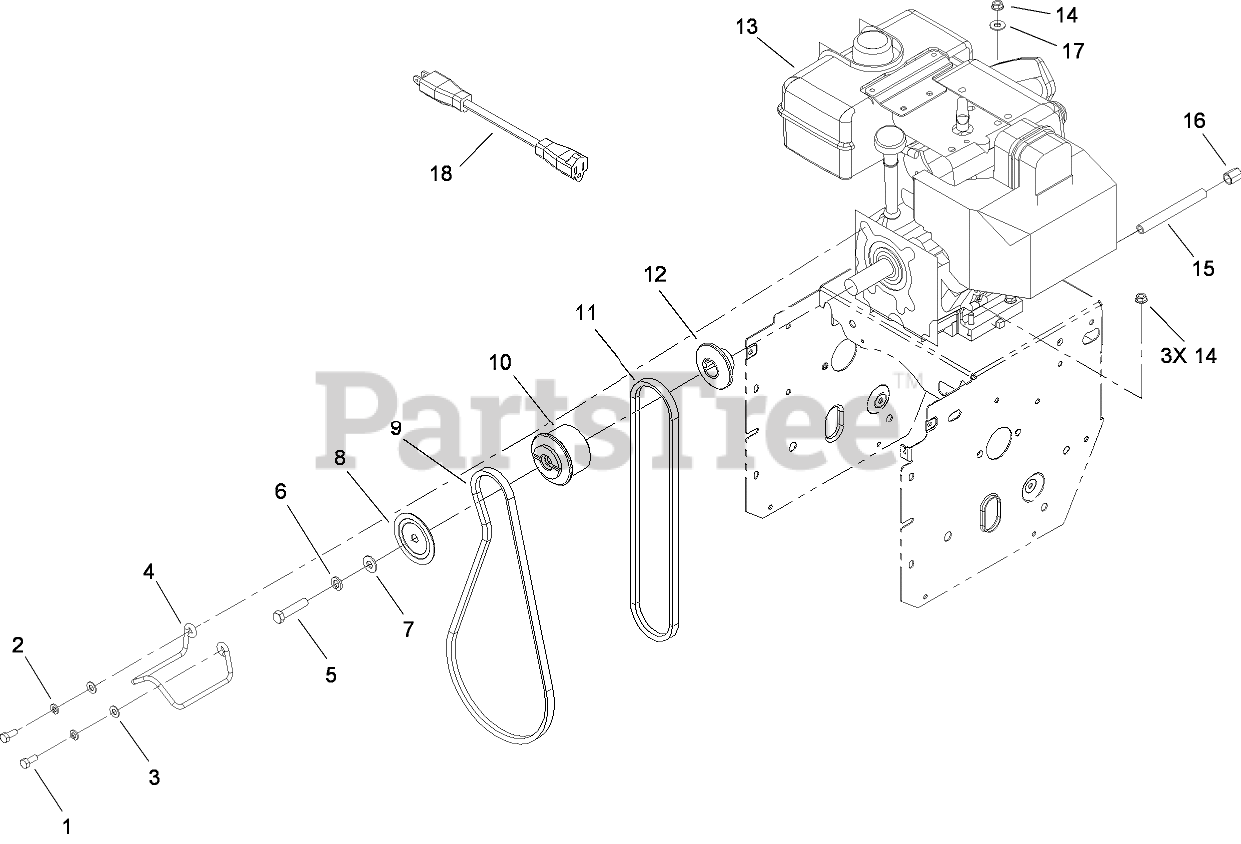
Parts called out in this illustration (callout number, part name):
1	SCREW-HH
2	WASHER-LOCK
3	WASHER-PLAIN
4	GUIDE-BELT
5	SCREW-HH
6	WASHER-LOCK
7	WASHER-FLAT
8	SHEAVE-HALF, IMPELLER
9	BELT-V
10	PULLEY-ENGINE, CENTER
11	V BELT-TRACTION
12	SHEAVE-HALF, TRACTION
14	NUT-HF
15	NIPPLE-PIPE
16	CAP-PIPE
17	WASHER-FLAT
18	CORD-EXTENSION
